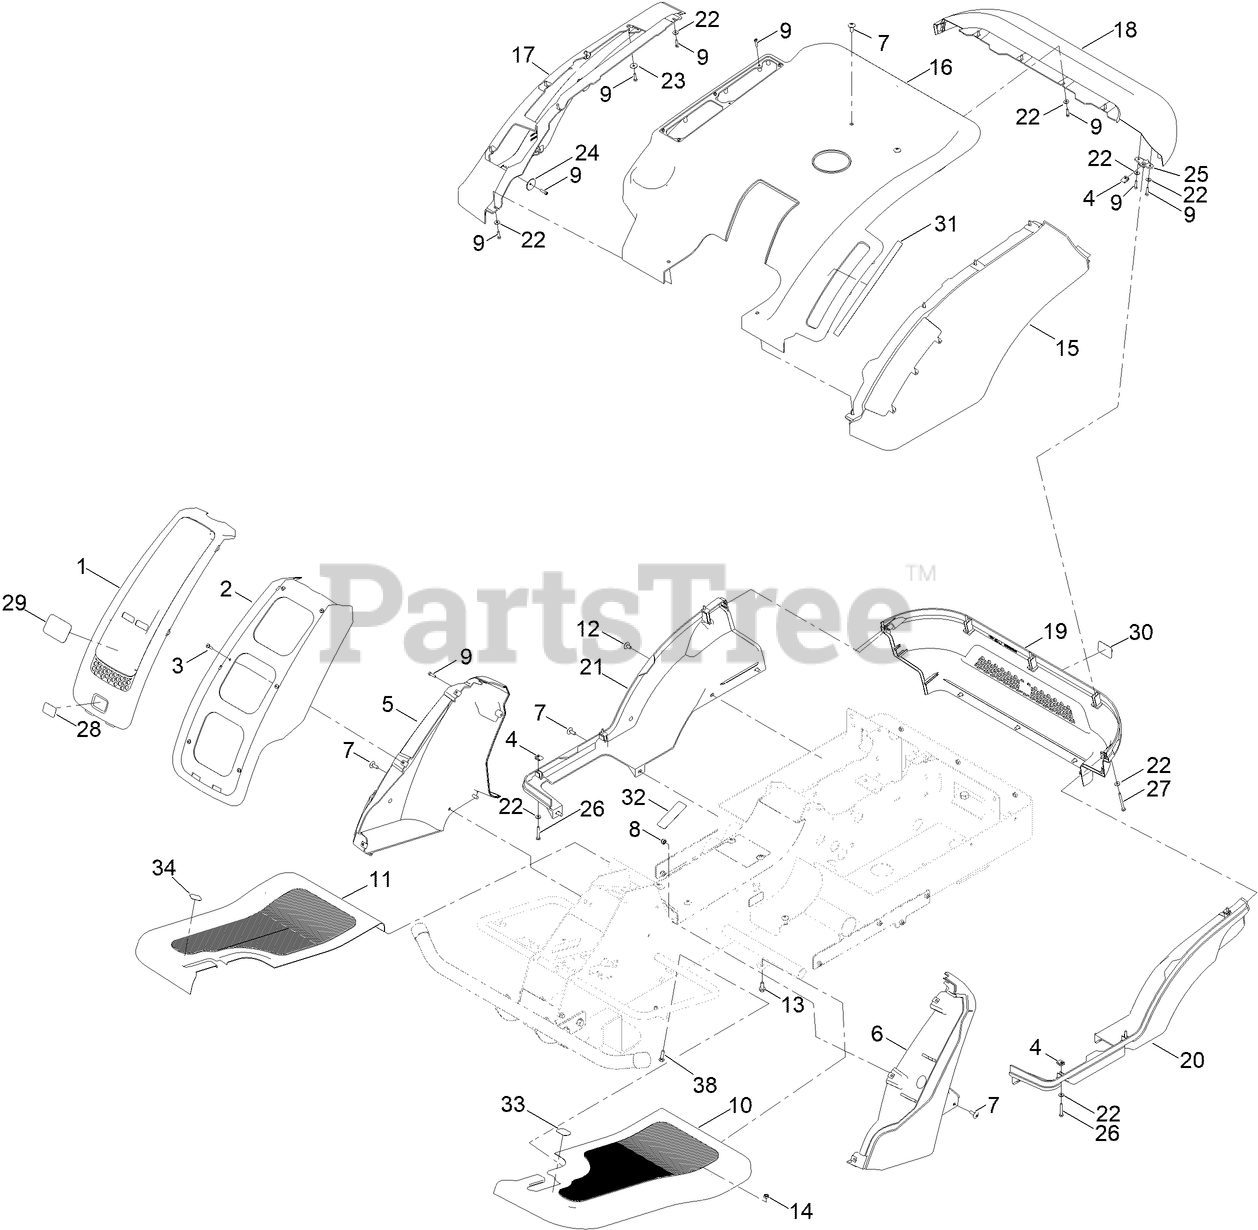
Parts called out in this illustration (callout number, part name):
1	FRONT PANEL, STEERING COLUMN
2	FRONT PANEL MOUTNING, STEERING COLUMN
4	CLIP, BOLT
5	RH PANEL, STEERING COLUMN
6	LH PANEL, STEERING COLUMN
8	NUT-NYLOC
10	PANEL FLOOR, LH
11	PANEL FLOOR, RH
12	CAP BOLT
13	SCREW-HHF
15	COVER, LH/MIDDLE
16	COVER, TOP
17	COVER, RH/MIDDLE
18	COVER, TOP/REAR
19	COVER, MIDDLE/REAR
20	COVER, RH/BOTTOM
21	COVER, LH/BOTTOM
22	WASHER
23	WASHER
24	WASHER, BENT
25	MOUNTNG BRACKET, REAR PANEL
26	BOLT PH
27	BOLT PH
28	DECAL - ERIDER BATTERY
29	DECAL - TORO LOGO
30	DECAL - TORO LOGO
31	DECAL - HOC
32	DECAL - PARKING BRAKE
33	DECAL - BRAKE
34	DECAL - PROPEL
